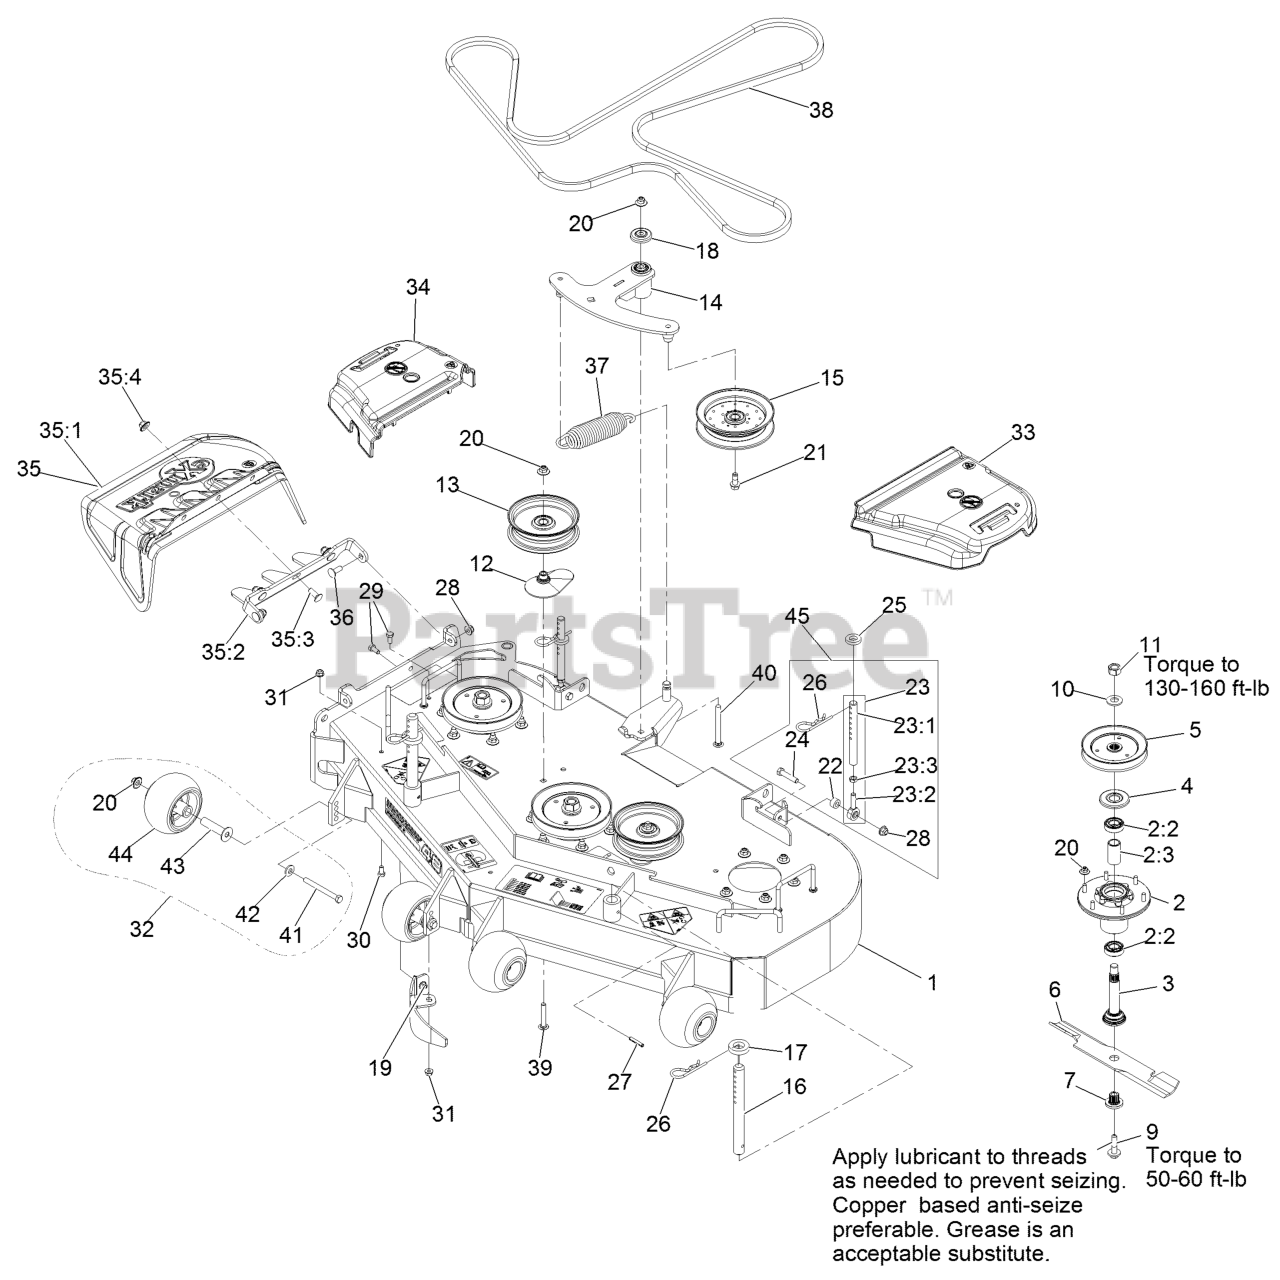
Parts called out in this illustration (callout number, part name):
1	ASM, DECK 48" W/DECALS
2	ASM-CUTTER HSG WITH BEARINGS
2:2	BEARING-BALL
2:3	SPACER-BEARING
3	ASM-SPINDLE AND SEAL
4	GUARD,BEARING TOP .989
5	SHEAVE,BLADE DRIVE 5.90
7	BUSHING,SPLINED
9	SCREW,SEMS 1/2-20 X 2.19
11	NUT-HEX
12	SPACER-PULLEY
13	IDLER-PULLEY, FLAT
14	ASM, DECK IDLER
16	ROD,DECK SUPPORT
17	SPACER-DECK SUPPORT
18	GUARD-TOP
19	BAFFLE, DOGLEG
20	Nut-Nyloc 3/8-16 Flg
21	SCREW-HFH
23:1	LINK,SUPPORT
23:2	BALLJOINT
23:3	NUT-HJ
24	SCREW-HH
26	PIN,HAIR COTTER
28	NUT-HF, NI
29	SCREW-HH
30	SCREW-HH
31	NUT-HF, NI
32	KIT, ANTI-SCALP ROLLER
33	COVER-BELT, LH
34	COVER-BELT, RH
35	ASM, DISCHARGE CHUTE
35:1	CHUTE,DISCHARGE
35:2	Bracket, Discharge Chute
35:3	SCREW-CARR
35:4	Nut-Nyloc 3/8-16 Flg
36	SCREW-CARR
37	SPRING-EXTENSION
38	BELT, DECK
39	BOLT-CARR, SHORT NECK
40	SCREW-CARR
41	SCREW-HH 3/8-16 X 3 3/4 GR 8
42	WASHER-BELLEVILLE
43	AXLE, ROLLER
44	ROLLER-SCALP, ANTI
45	KIT,SUPPORT LINK W/PIN
